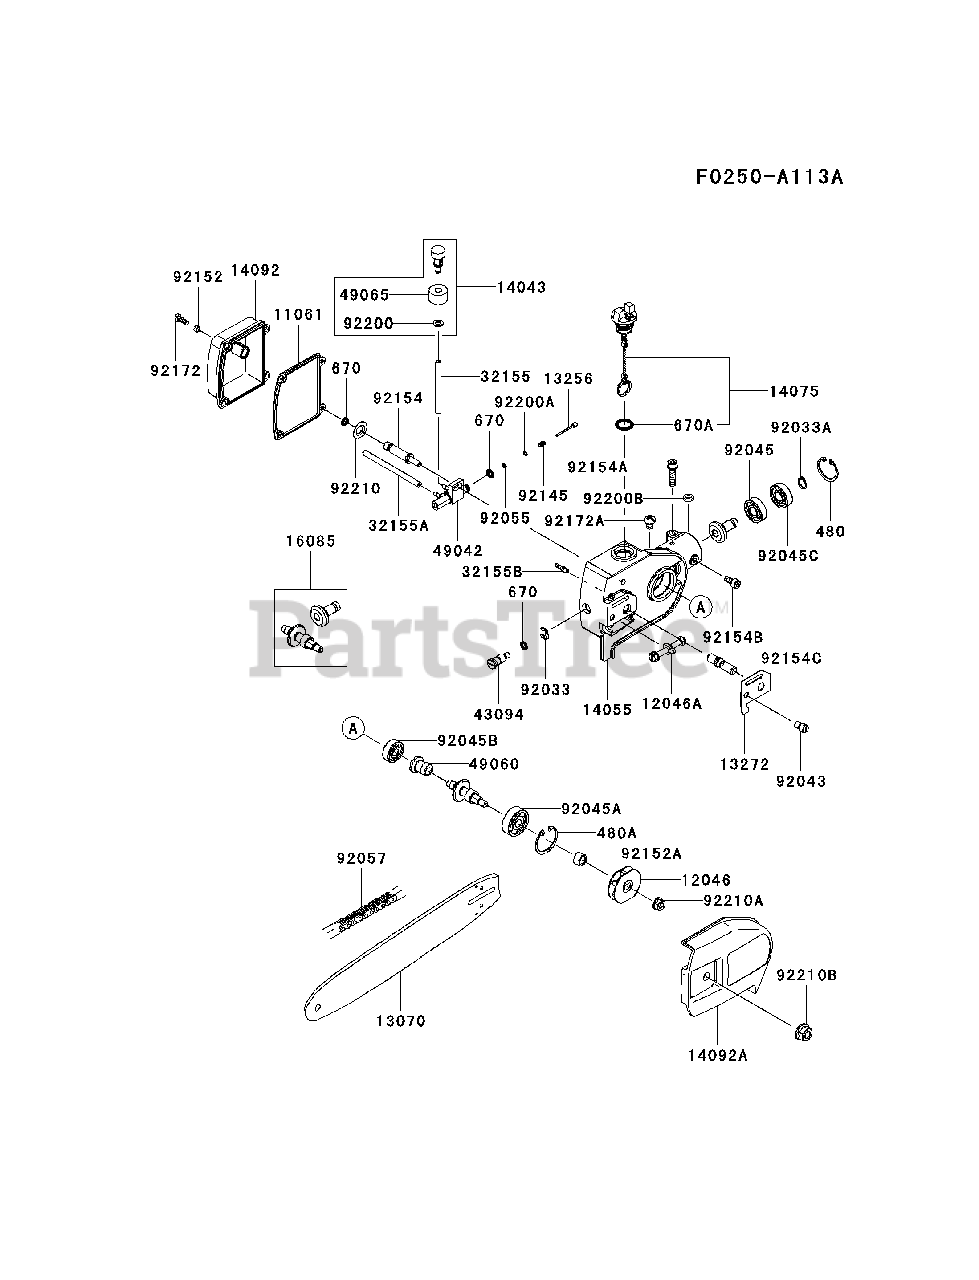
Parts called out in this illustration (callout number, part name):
480	CIRCLIP-TYPE-C,24MM
480A	CIRCLIP-TYPE-C,28MM
670	O RING,5MM
670A	O RING,15MM
92210B	NUT,CHAIN BAR CLAMP
